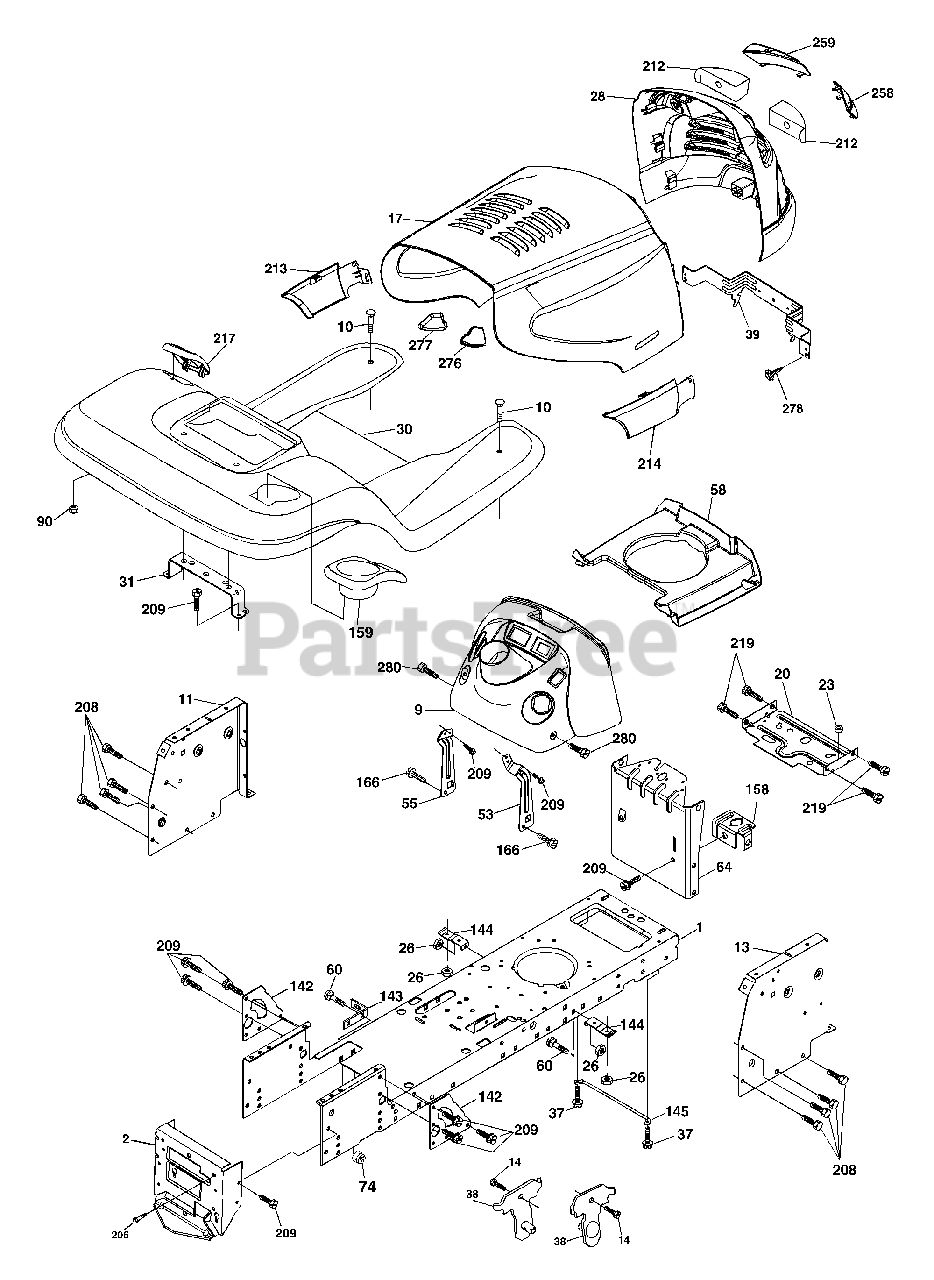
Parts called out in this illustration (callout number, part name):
1	Chassis Stamping
9	Dash P/L Husq
10	Bolt Rdhd Sqnk 3/8-16 unc x 1
11	Panel Dash Lh
13	Panel Dash Rh
14	Screw Thdrol 3/8-16 x 1/2
17	Hood
20	Plate Battery
23	Bushing Snap
26	Nut Lock w/Insert 3/8-16 unc
28	Grille Lens Asm
30	Fender
37	Screw Thdrol 5/16-18 x 1/2
38	Bracket Asm Pivot Mower Rear
39	Bracket Pivot Laser
53	Bracket Dash RH
55	Bracket Dash LH
60	Bolt RDHD SQNK 3/8-16 x 3/4
64	Dash Lower Stlt
74	Nut Crownlock 3/8-16
90	Nut Self-Thd. Wsh-Hd 1/4 Zinc
142	Plate Reinforcement Stlt
143	Bracket Swaybar Chassis
144	Bracket Ft Rest
145	Rod Pivot Chassis Hood
158	Bracket Parking Brake
159	Cupholder YTGT Grey
206	Bolt Shoulder 5/16-18 TT
208	Screw Thdrol 3/8-16 x 1/2 Ty-TT
209	Screw Hex Wsh Thdr. 3/8-16 x 3/4 BL
212	Insert, Grille
213	Skirt Side LH
214	Skirt Side RH
217	Console Fuel Window STLT
219	Screw Hexwsh Thdr 3/8-16 x 3/4
258	Lens Husq. Laser LT Clear RH
259	Lens Husq. Laser LT Clear LH
276	Bumper Hood RH
277	Bumper Hood LH
278	Screw Quadx Wshd #10-14 x 1
280	Screw 3/8-16 x 1
